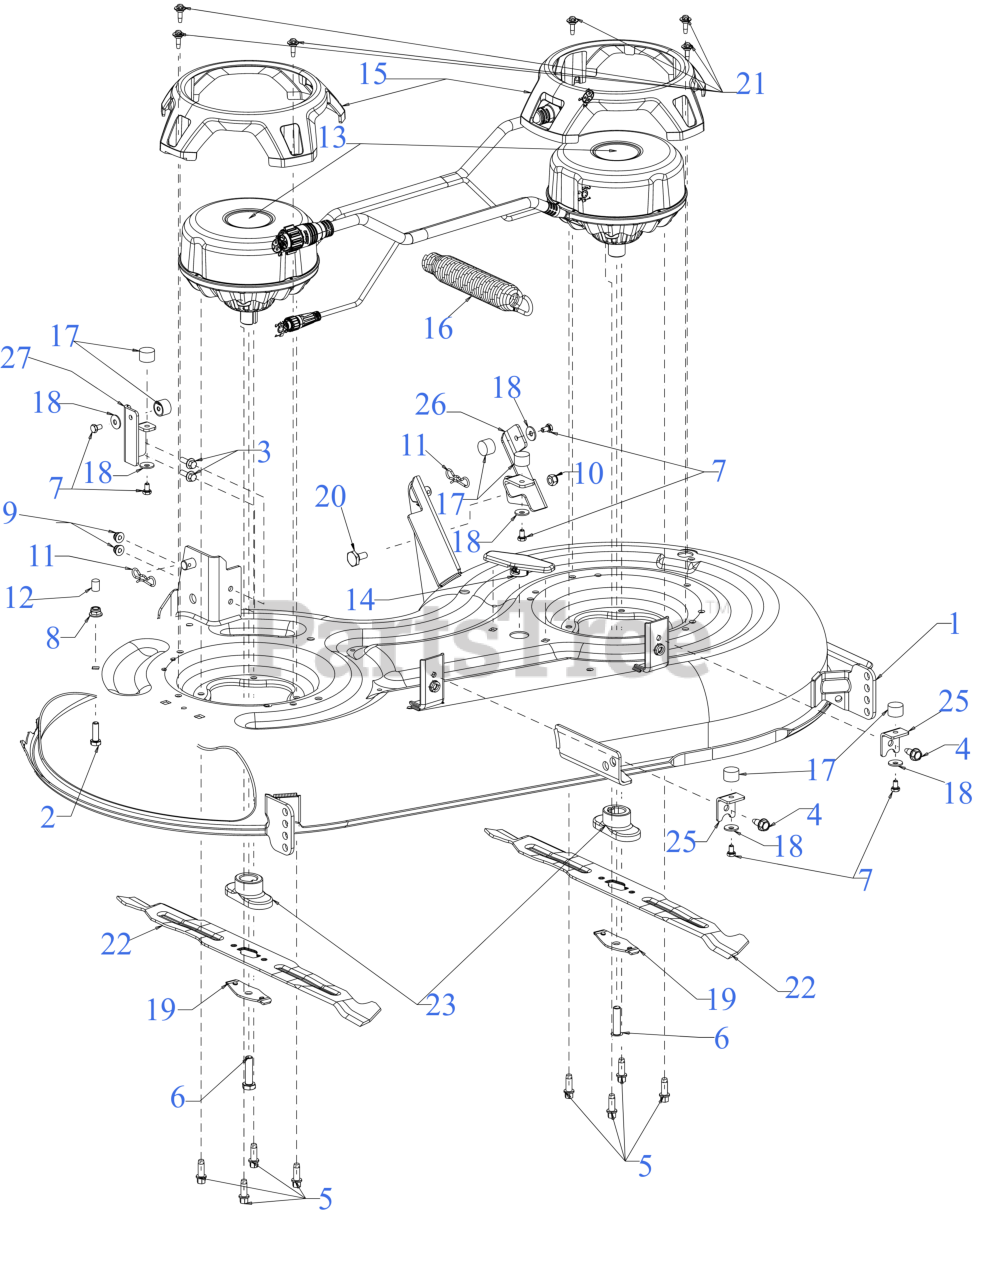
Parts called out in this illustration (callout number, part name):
1	42" DECK
2	SCREW 5/16-18 x 1.0 GR5
3	SCREW 1/4-20 x .75 GR5
4	SCREW M8-1.25 x .750
5	SCREW 5/16-18 x .875
6	SCREW 3/8-24 x 1.50 GR8
7	SCREW M6-1.0X10MM GR8.8
8	FLANGE LOCK NUT 5/16-18
9	FLANGE LOCK NUT
11	BOW TIE COTTER PIN
13	48V ELECTRIC DECK MOTOR
15	MOTOR COVER
16	LIFT ASSIST SPRING (SMALL)
18	SPRING WASHER BELL
19	BLADE BELL SUPPORT
20	SHOULDER SCREW
21	SHOULDER SCREW M6-1 .368 X.115
22	21.18" MULCH BLADE (S SHAPE CENTER HOLE)
23	BLADE ADAPTER (#6 X 1.19 W/S)
25	UPSTOP BRACKET
26	UPSTOP BRACKET (LH)
27	UPSTOP BRACKET (RH)
